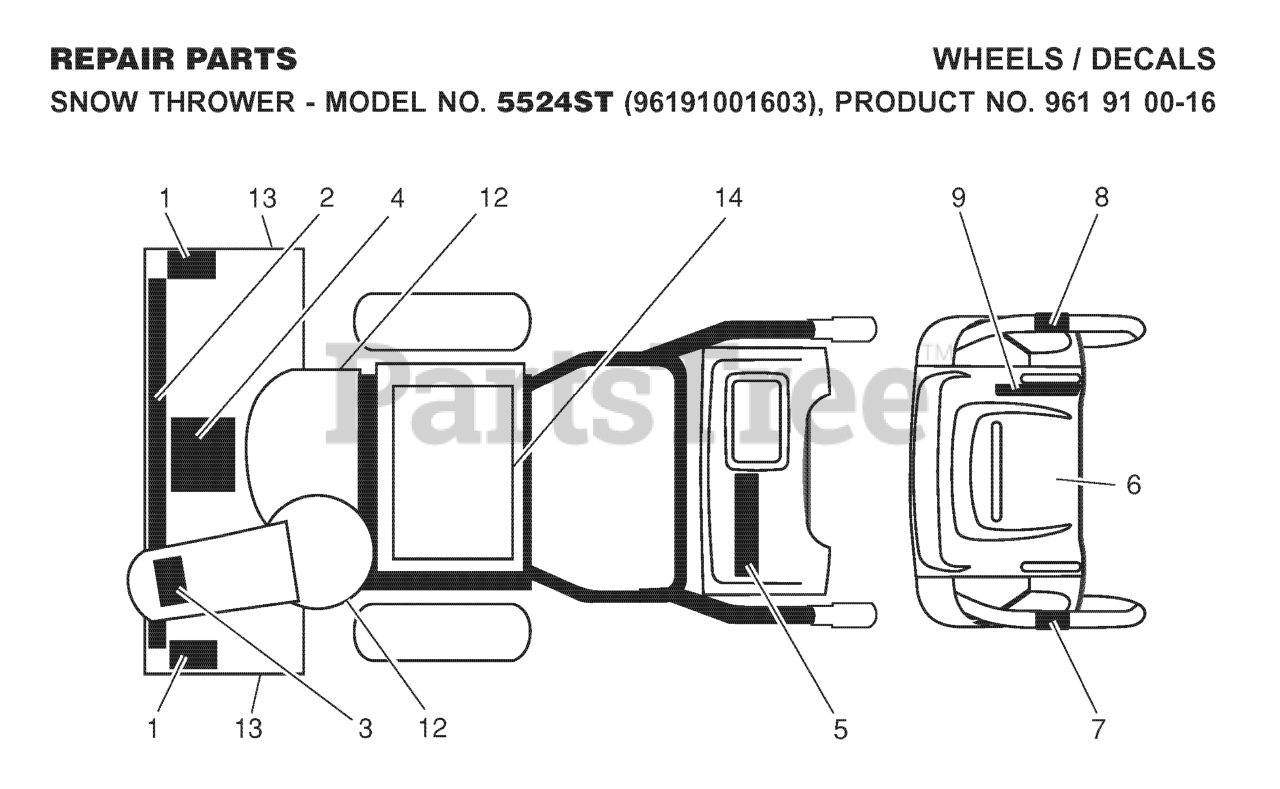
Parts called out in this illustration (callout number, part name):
1	DECAL.AUGER.SAFETY.
3	DECAL.CHUTE.SAFETY.
4	DECAL.AUGER."
6	DECAL.CONSOLE.INSTRUCTION
12	DECAL.BELT.GUARD.
13	DECAL, HUSQVARNA
14	DECAL.FENDER
